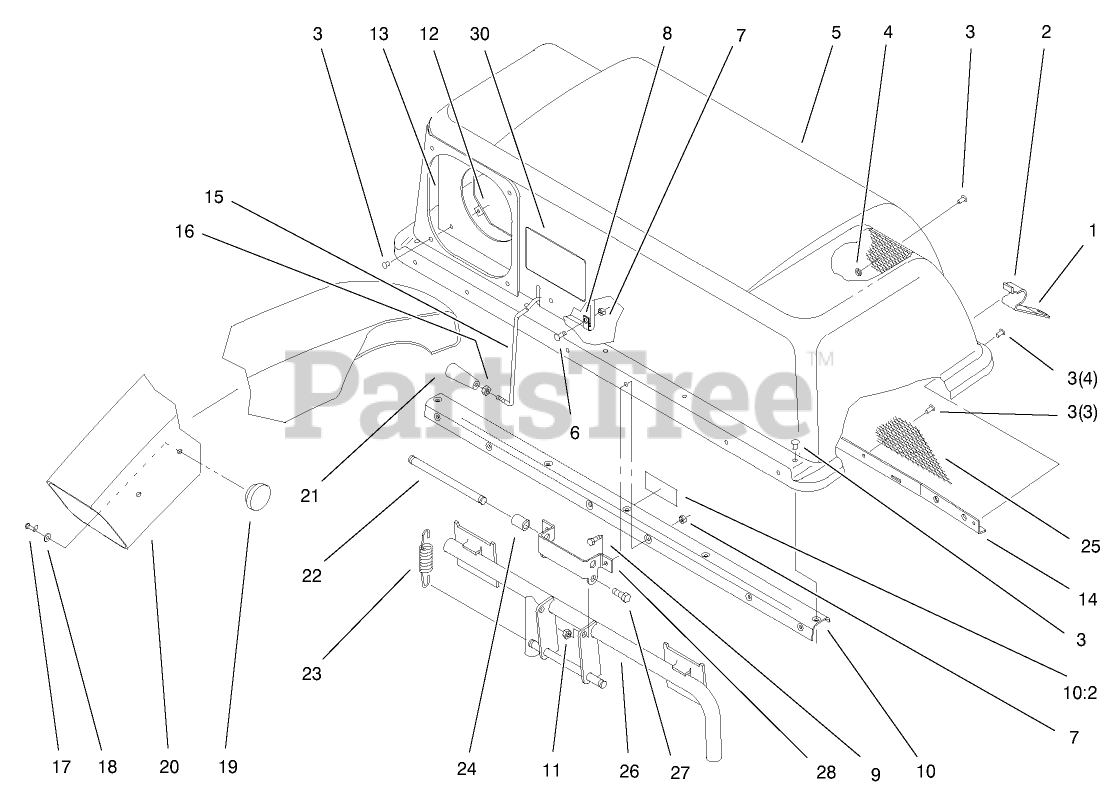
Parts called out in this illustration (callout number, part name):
2	LATCH-BAGGER, TOP
3	RIVET-BLIND
4	WASHER-FLAT
5	TOP-BAGGER
6	SCREW-HH
7	NUT-LOCK, NI
8	CLAMP
10	STIFFENER ASM
10:2	DECAL-CAUTION
11	NUT-LOCK, NI
12	CLAMP-SEAL
13	SEAL-CHUTE
14	SUPPORT-SCREEN
15	FEELER-FILL, BAG
16	NUT-JAM
17	SCREW-PPHTF
18	WASHER-PLAIN
20	CHUTE-DISCHARGE
21	HANDLE-TAPERED
22	PIN-SPRING
23	SPRING-EXTENSION
24	SPACER
25	SCREEN-BAGGER
26	FRAME ASM
27	SCREW-HH
28	HINGE-BAG, TOP
30	DECAL
